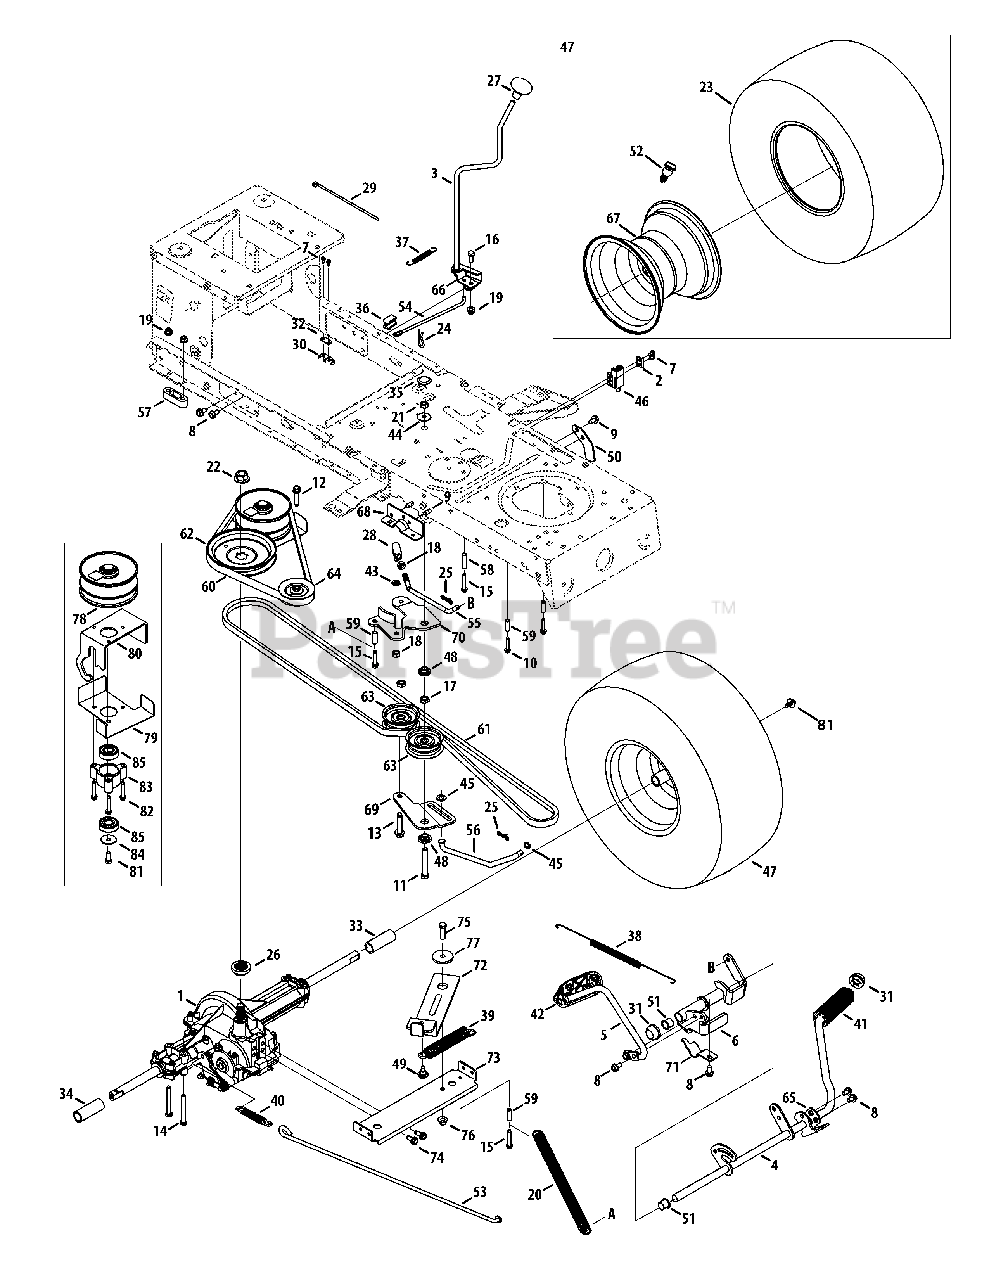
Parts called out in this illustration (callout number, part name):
1	Transmission Drive Assembly
2	Plate Switch
3	Shaft Lever Assembly
4	Pedal Assembly, drive
5	Pedal Assembly, control
6	Pedal Bracket Assembly
7	Screw, 8-18:0.500
8	Screw, 5/16-18 x .750
9	Screw, 5/16-18 x 0.625
10	Screw, 1/4-20 x 1.250
11	Hex Screw, 3/8-16 x 2.50
12	Screw, 3/8-16 x 1.500
13	Screw, 3/8-16 x 1.750
14	Hex Screw, 5/16-18 x .625
15	Screw, 1/4-20 x 1.75
16	Hex Screw, 5/16-18 x .75
17	Jam Nut, 7/16-20
18	Hex Nut, 3/8-24
19	Flangelock Nut, 5/16-18
20	Spring Extension, .56 OD x 12.05
21	Nut, 3/8-16, Centerlock
22	Flange Nut, 9/16-18
23	Tire, 20 X 8 X 8, 46"
24	Cotter Pin INT- .125 DIA
25	Bow-Tie Cotter Pin, 72
26	Pulley Hub, 5/8 SPLINE
27	Shift Knob
28	Ball Joint
29	Cable tie
30	Short Spring Switch
31	Push Cap, 5/8
32	Plate Insulator Nut
33	Sleeve, .758 x .821 x 3.3125
34	Sleeve, .758 x .821 x 2.4375
35	Plug, 7/8
36	Shift Plate Bearing
37	Spring Extension, .38 OD x 3.25 LG
38	Spring Extension, .70 OD X 12.00
39	Spring Extension, .97 Od X 6.18 Lg
40	Spring Extension, .59 OD x 4.00 LG
41	Foot Pad, 4.0 Long
42	Control Pad
43	Lock Washer 3/8
44	Flat Washer, .406 x 1.920 x .060
45	Flat Washer, .375 X .738 X .063
46	Switch Interlock
47	Wheel, 20 x 8 x 8 - Grey, 46"
48	Shoulder Spacer, 1.00 X .38 X .38
49	Shoulder Screw, .43 x .29, 5/16-18
50	Stop Pedal Plate
51	Flng Bearing .63 Id x .695 Od X .60
52	Valve, tubeless Air
53	Brake Rod
54	Shift Rod, 46"
55	Idler Adjustment Rod
56	Transmission Bypass Rod
57	Spacer, T-Axle .68
58	Spacer, .260 X .372 X 1.420 Lg
59	Spacer, .260 X .375 X 1.030 Lg
60	V Belt, 5L 40.9 Poly
61	V Belt, 5L, 90.93 Poly
62	V Pulley 7.25 DIA SPUN
63	Idler Pulley
64	Idler Pulley
65	Pedal Support Bracket
66	Shaft Adjust Bracket
67	Rim, 8.0 X 7.0 X .750
68	Frame Pedal Bracket, Rh
69	Center Idler Bracket
70	Idler Bracket
71	Pedal Support Bracket
72	Idler Bracket Assembly
73	Bracket Assembly
74	Screw, 5/16-18 x 0.750
75	Hex Screw, 3/8-16 x 1.25
76	Flangelock Nut, 3/8-16
77	Shoulder Spacer, .8840 X .190
78	Variable Speed Pulley Assembly
79	Belt Keepr Assembly
80	Bracket Assembly
81	Screw, 5/16-24 x .750
82	Screw, 1/4-20 x 1.500
83	Bearing Cup
84	Flat Washer, .330 X 1.25 X .06
85	Ball Bearing, 17 x 40 x 12
